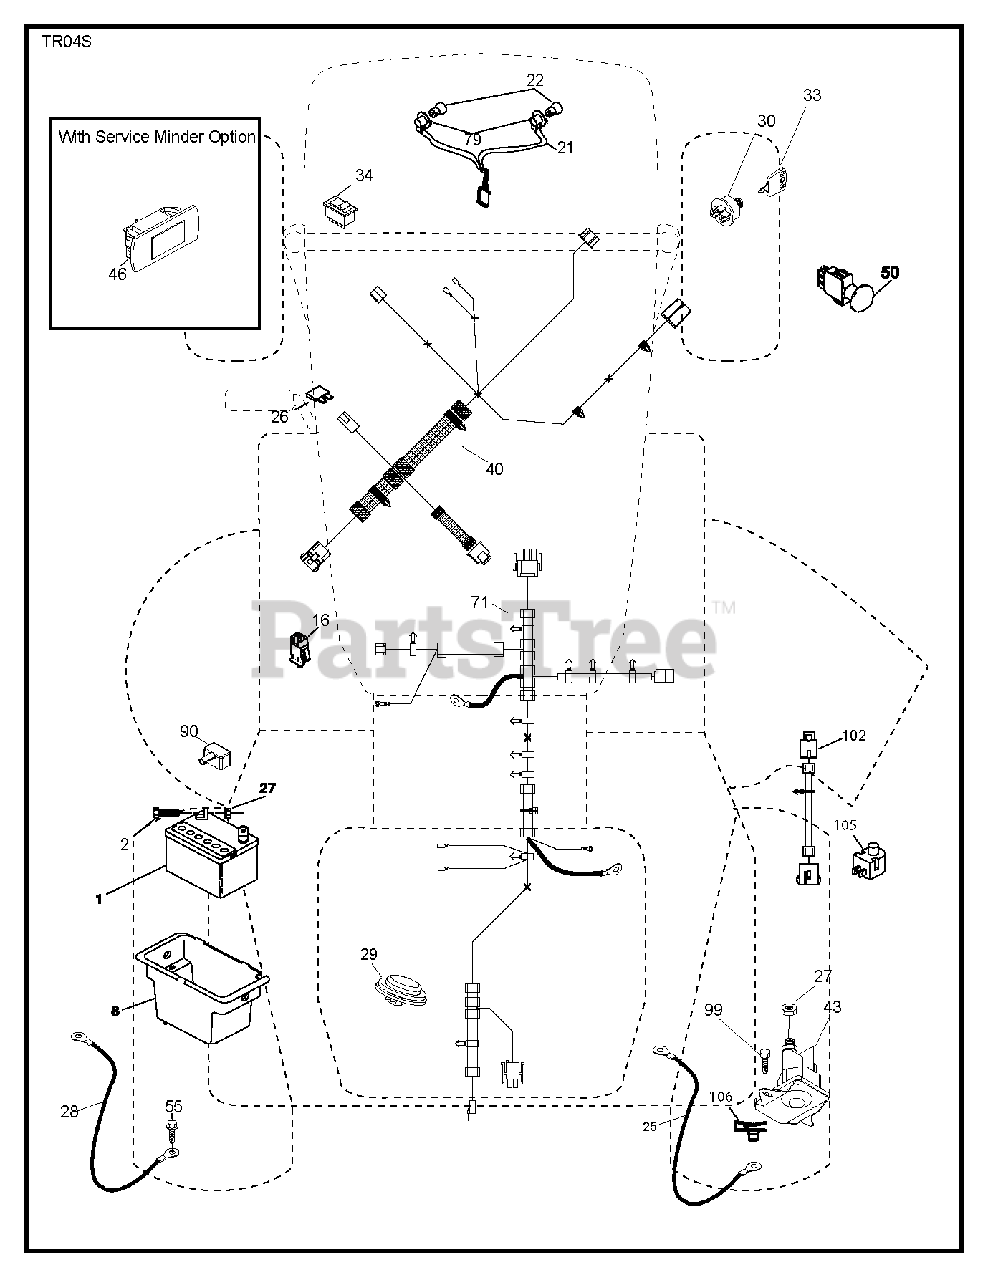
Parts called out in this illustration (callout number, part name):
1	REPL BY 532 12 38-99
2	BOLT.HEX.1/4.X.3/4.DICHROMATE
8	BOX.BATTERY.MNT.REAR.L
16	SWITCH INTERLOOK PUSH-IN
21	HARNESS.LIGHT W/4152J BULBS
22	LIGHTBULB
25	CABLE.BATT.RED.8GA.17
26	FUSE 20AMP
27	NUT
28	CABLE.GROUND.REAR.BATTERY.8G
29	SWITCH.SEAT.DELTA.OPC.
30	SWITCH.IGN.DELTA.W.LGH.ROS
33	KEY.CHAIN.BLISTER.PACK.GEN.USA
34	SWITCH LT
40	HARNESS.TEX.DASH.ELEC.REAR BAT
43	SOLENOID.W/BRASS.PLUNGER
46	Hour Meter Gauge
50	SWTICH.PTO.8.TERMINAL
55	SCREW 5/16"
71	HARNESS.TEX.CHSSIS.REAR.BATT
79	BULB HOLDER ASM.
90	COVER.TERMINAL.BATTERY
99	SCREW HEXWSHR 1/4-20X3/4
102	HARNESS.PIGTAIL.VARIATOR.SD
105	REVERSE SWITCH
106	1/4-20 U NUT
